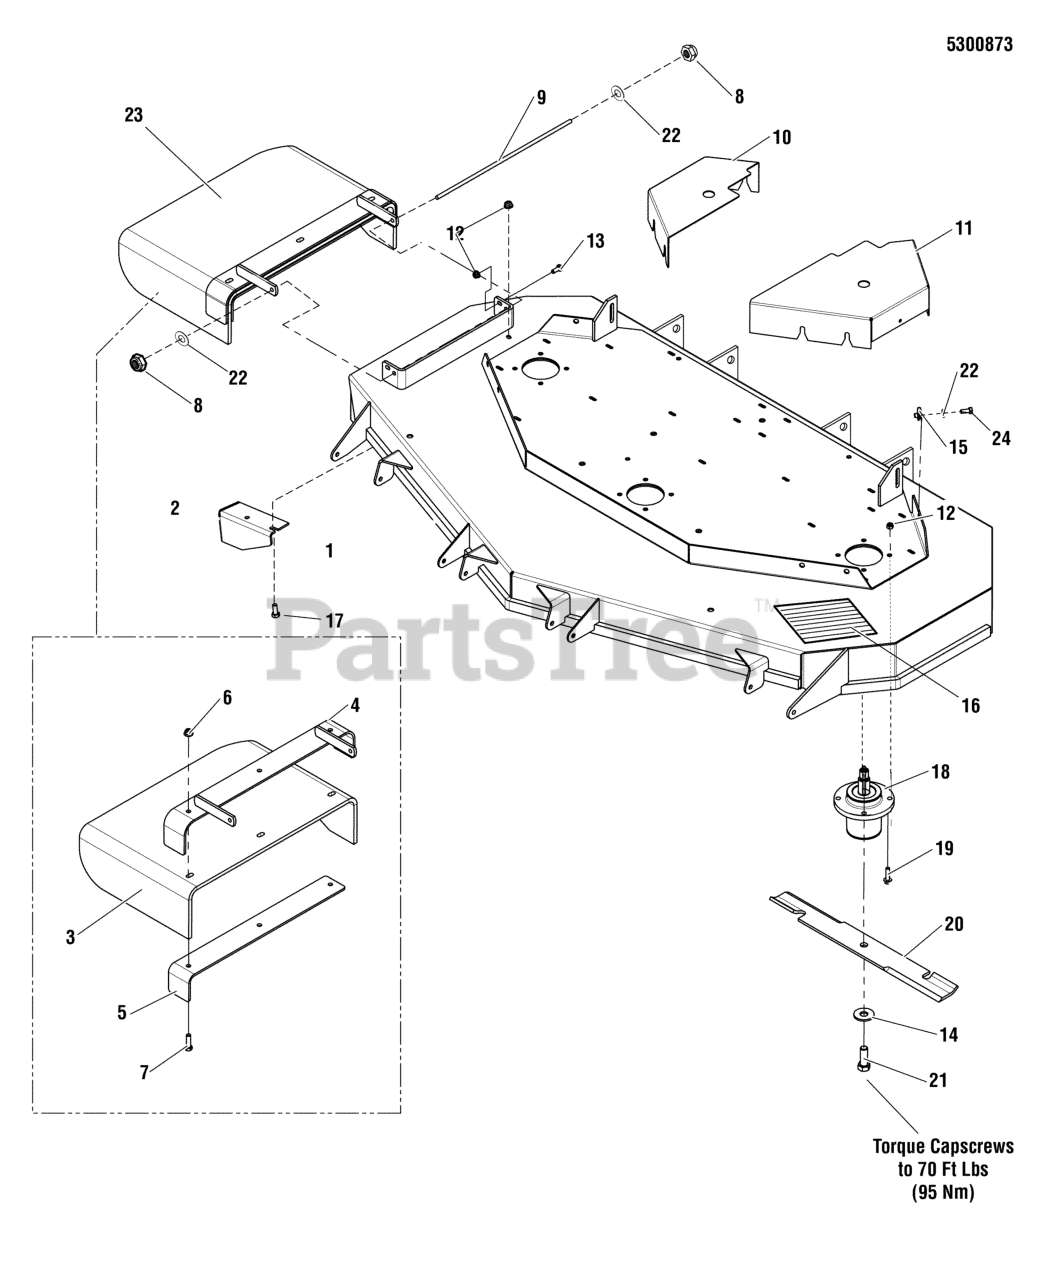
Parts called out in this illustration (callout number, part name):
1	DECK SHELL W/DECALS 61" SNP PRO
2	PLATE, DEFLECTOR - BLK
3	CHUTE, DISCHARGE, RUBBER, 61/72
4	WELD, FRAME, CHUTE, 61 - RED
5	SUPPORT, DISCHARGE CHUTE - BLK
6	NUT, 3/8-16 HEX NYLOCK FLANGE
7	BOLT, 3/8-16 X 1-1/2" GD5 CZ
8	NUT, 5/16-24 HEX NYLON LOCK
9	ROD MOUNT, CHUTE 61"
10	GUARD, 61, RH - RED
11	GUARD, 61 - LH - RED
12	NUT, 5/16-18 HEX NYLOCK FLANGE
13	BOLT, 5/16-18 X 3/4 GD5
14	WASHER, 5/8 USS
15	BODY CLIP, 5/16-18-7GA MATERIAL
16	SAFETY WALK, 9.75 X 6.00
17	BOLT, 5/16-18 X 3/4, CARRIAGE
18	ASSM, SPINDLE, LOW PROFILE
19	BOLT, 5/16-18 X 1 1/4 FLANGE
20	BLADE SET, 61 DECK (SET OF 3 BLADES)
21	BOLT, 5/8-11 X 1-3/4" GD8
22	WASHER, 5/16" SAE
23	KIT, DISCHARGE CHUTE, 61/72, SNP PRO (SV)
24	BOLT, 5/16-18 X 1 GD5 YZ
